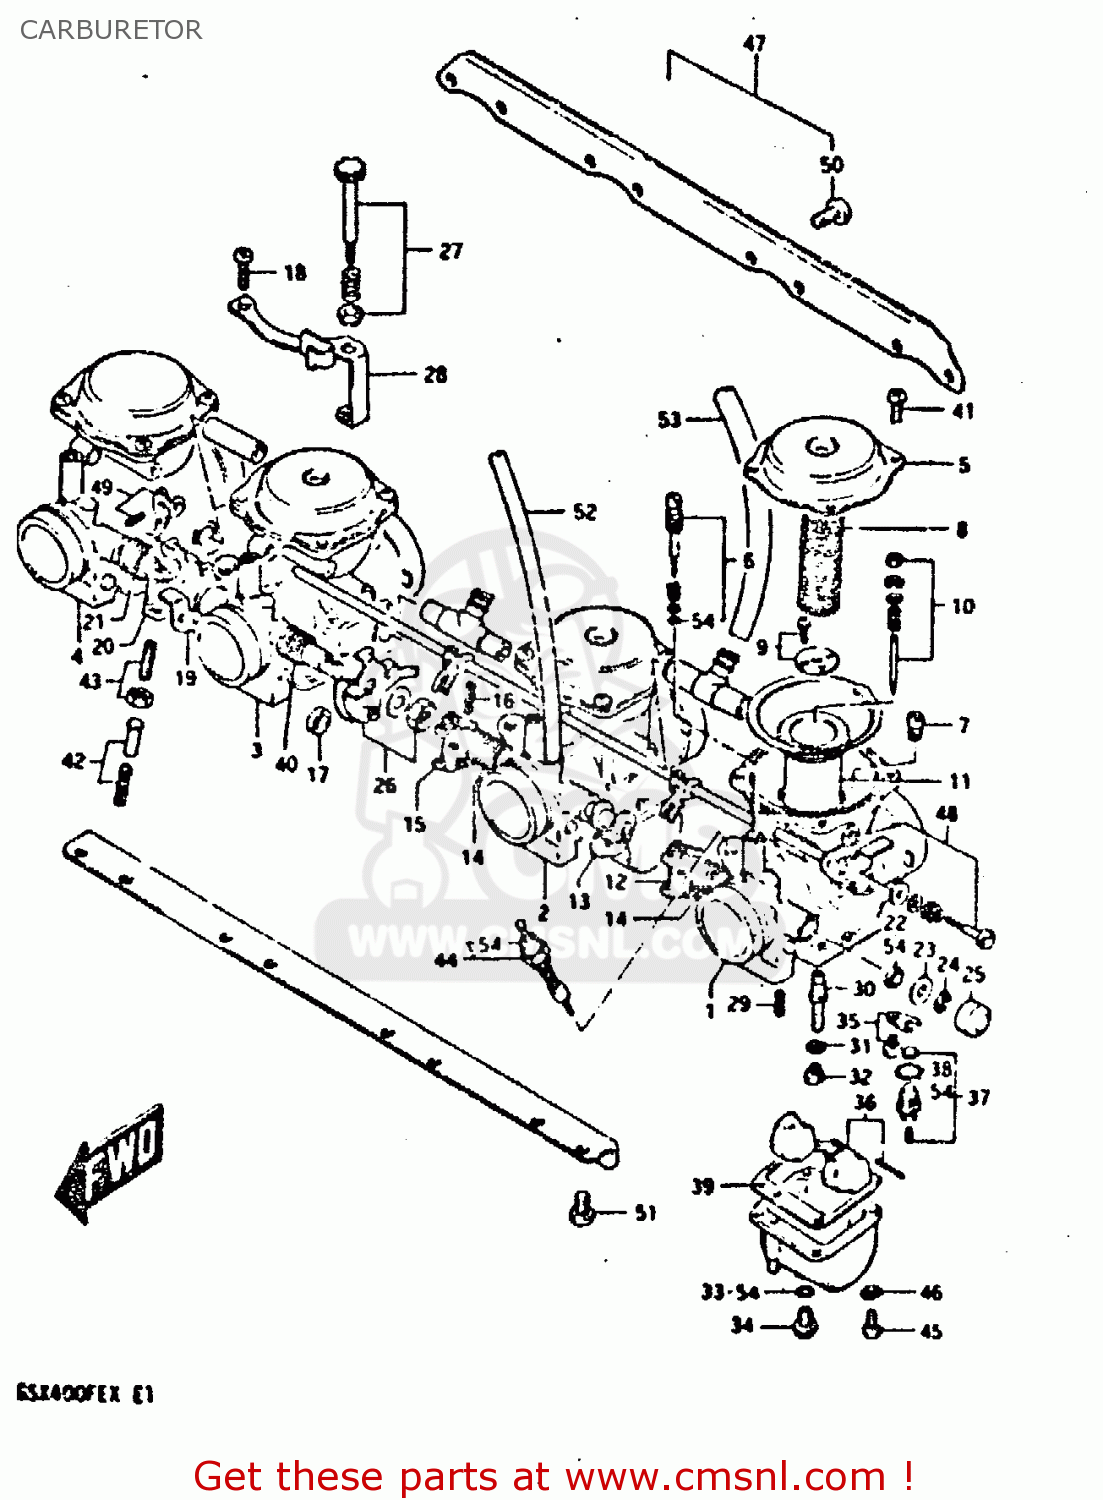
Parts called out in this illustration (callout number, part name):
1	CARBURETOR, NO. 1
2	CARBURETOR, NO. 2
3	CARBURETOR, NO. 3
4	CARBURETOR, NO. 4
5	COVER
6	ADJUSTER SET
7	JET,MAIN(180)
8	SPRING
9	PLATE SET
10	JET NEEDLE SET
11	DIAPHRAGM ASSEMBLY
12	SHAFT, THROTTLE
13	SHAFT, THROTTLE
14	SPRING
15	LEVER, THROTTLE
16	PIN,THROTTLE SHAFT
17	SPACER,THROTTLE SHAFT
18	SCREW
19	SHAFT, THROTTLE
20	SHAFT, THROTTLE
21	SPRING
22	SEAL
23	GASKET,THROTTLE SHAFT (NAS)
24	E RING
25	CAP
26	THROTTLE LEVER SET
27	IDLE ADJUSTER SET
28	BRACKET, IDLE ADJUSTER
29	JET
30	JET, NEEDLE (P-O)
31	WASHER,NEEDLE NOZZLE
32	JET
33	GASKET (NAS)
34	PLUG,DRAIN
35	PLATE
36	FLOAT SET
37	VALVE ASSY,NEEDLE
38	O-RING,NEEDLE VALVE
39	GASKET,FLOAT CHAMBER (NAS)
40	SPRING,THROTTLE SHAFT
41	SCREW
42	SPRING SET
43	SCREW SET
44	STARTER PLUNGER SET
45	SCREW
46	LOCK WASHER
47	FLANGE SET
48	SCREW SET
49	STARTER LEVER SET
50	SCREW
51	SCREW 6X12
52	HOSE
53	HOSE, AIR VENT
54	GASKET SET (NAS)
